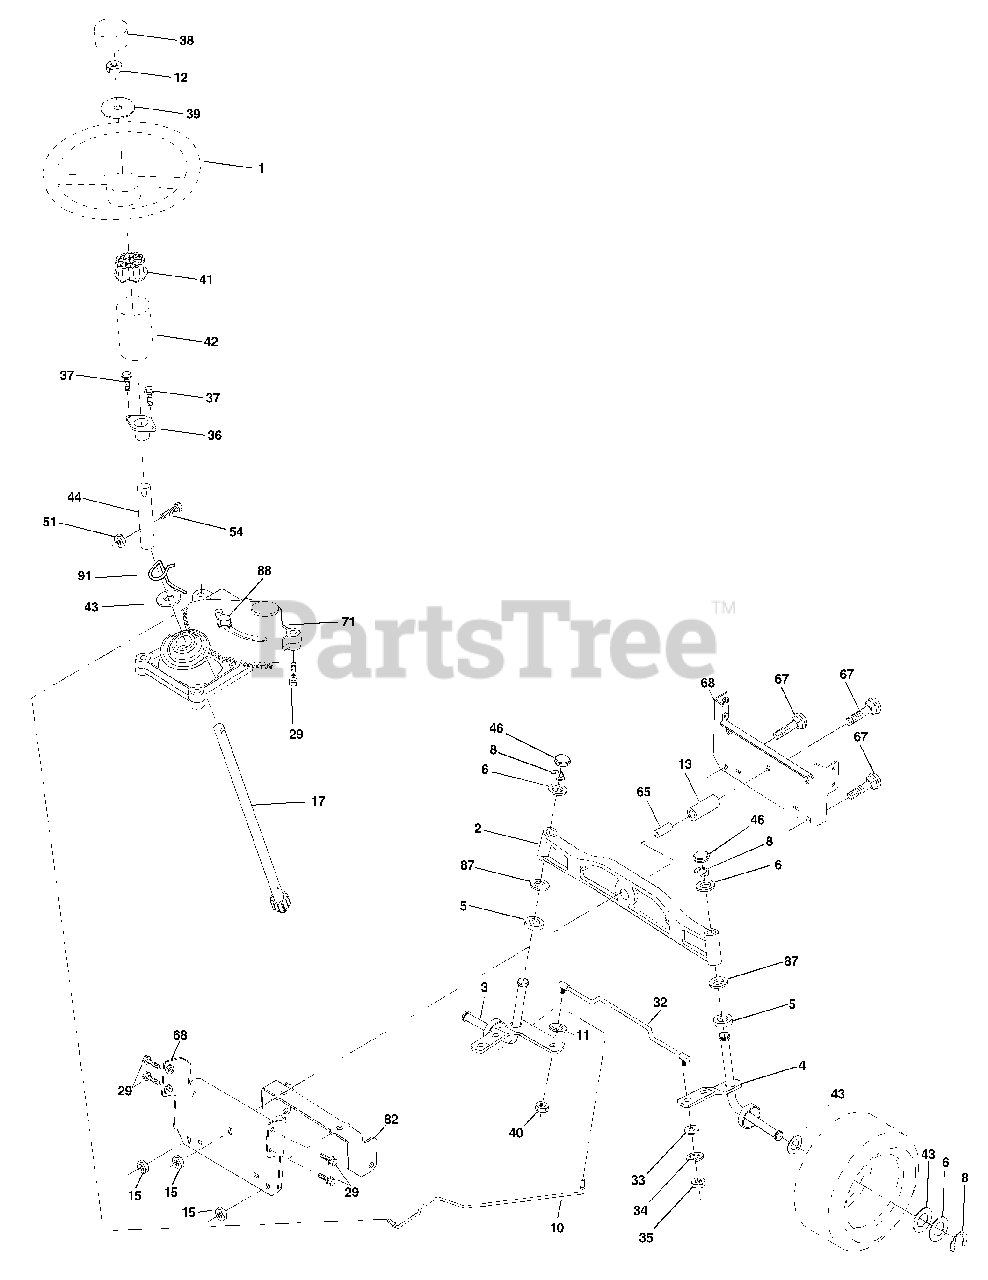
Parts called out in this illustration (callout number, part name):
1	Wheel Steering
2	Axle Asm Cast Iron LT
3	Spindle Asm LH
4	Spindle Asm RH
5	Bearing Race Thrust Harden
6	Washer 25/32 X 1-5/8 X 16 Ga
8	Ring Klip #t5304-75
10	Link Drag
11	Washer Lock Hvy Hlcl Spr 3/8
12	Nut Hex Jam Toplock 1/2-20 Unf
13	Spacer Brg. Axle Front
15	Nut Hex Flange Lock
17	Shaft Asm. Steering
29	Screw 3/8-16x.75
32	Rod Tie
33	Washer 11/32 x 3/4 x 16 Ga.
34	Washer Lock Hvy Hlcl Spr 5/16
35	Crownlock Nut 5/16-24
36	Bushing Strg
37	Screw
38	Insert Cap Strg Wh Au
39	Washer
40	Lock nut
41	Adaptor Wheel Strg
42	Boot Steering Dash
43	Washer 25/32 X 1 1/4 X 16 Ga
44	Extension Steering Shaft
46	Cap Spindle Fr Top Blk
51	Nut Crownlock 1/4-28
54	Bolt Hex 1/4-28 Unf x 1-1/4 Gr. 8
65	Brace Axle
67	Bolt Rdhd Sq 3/8-16 Unc x 2-1/4
68	Axle, Brace
71	Steering Asm.
82	Bracket Susp. Chassis Front
87	Washer Flat .781 x 1-1/2 x .14
88	Bolt Shoulder 7/16-20 Unc
91	Clip Steering
